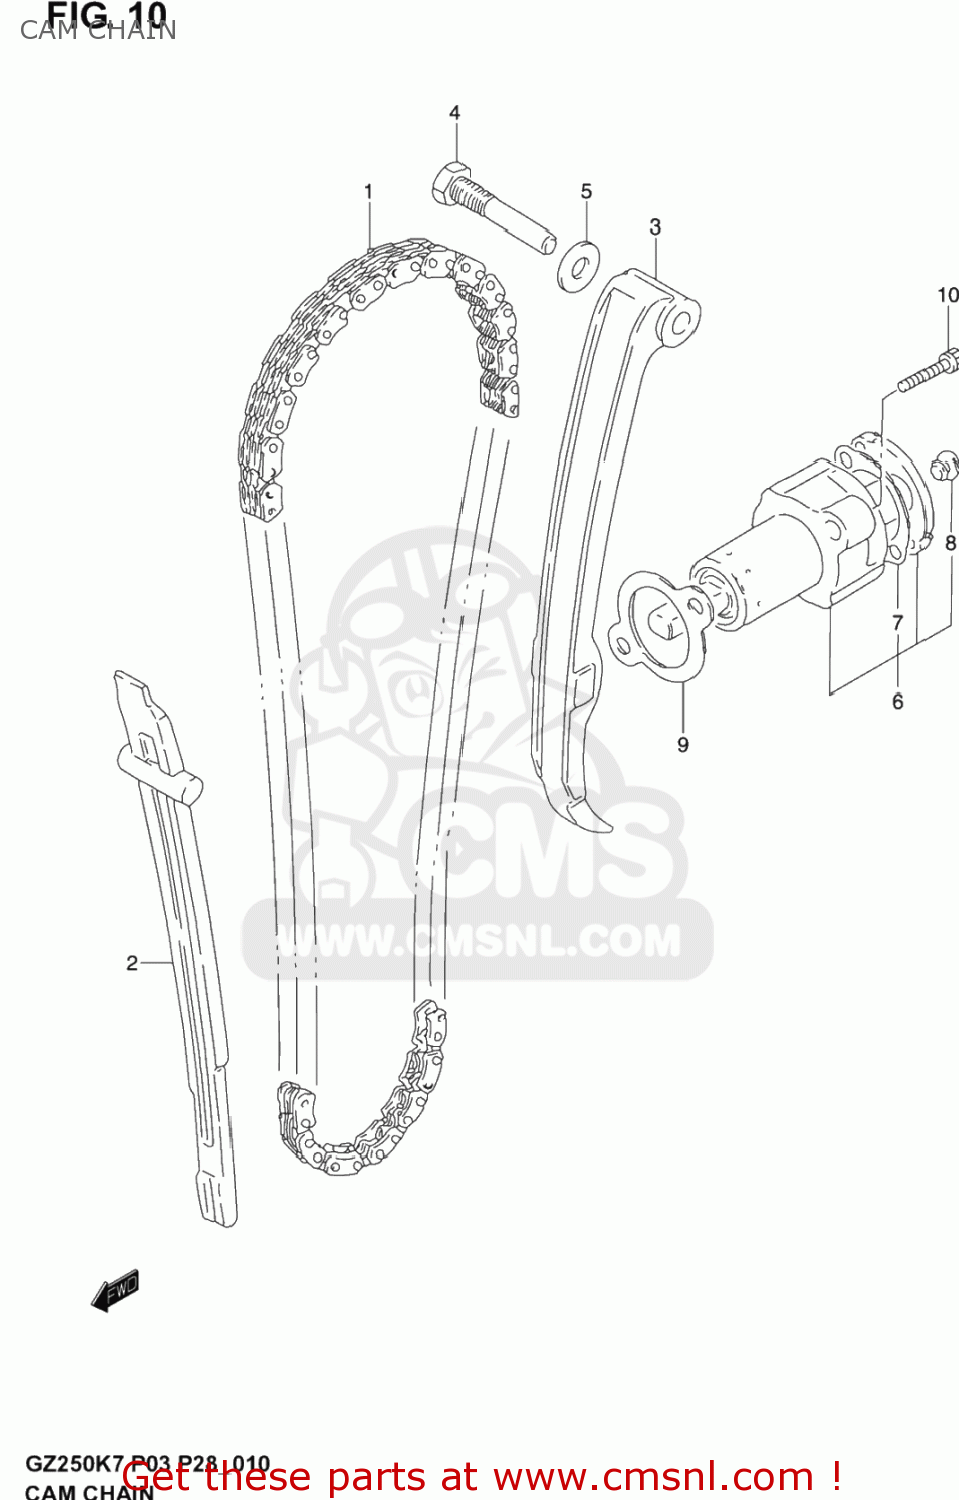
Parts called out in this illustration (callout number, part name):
1	CHAIN,CAMSHAFT DRIVE
2	GUIDE,CAM CHAIN
3	TENSIONER,CAM CHAIN
4	BOLT,CAM CHAIN TENSIONER
5	GASKET(8.2X14X1) (NAS)
6	ADJUSTER ASSY,TENSIONER
7	GASKET,ADJUSTER CAP (NAS)
8	PLUG,ADJUSTER
9	GASKET,TENSIONER ADJUSTER (NAS)
10	BOLT
